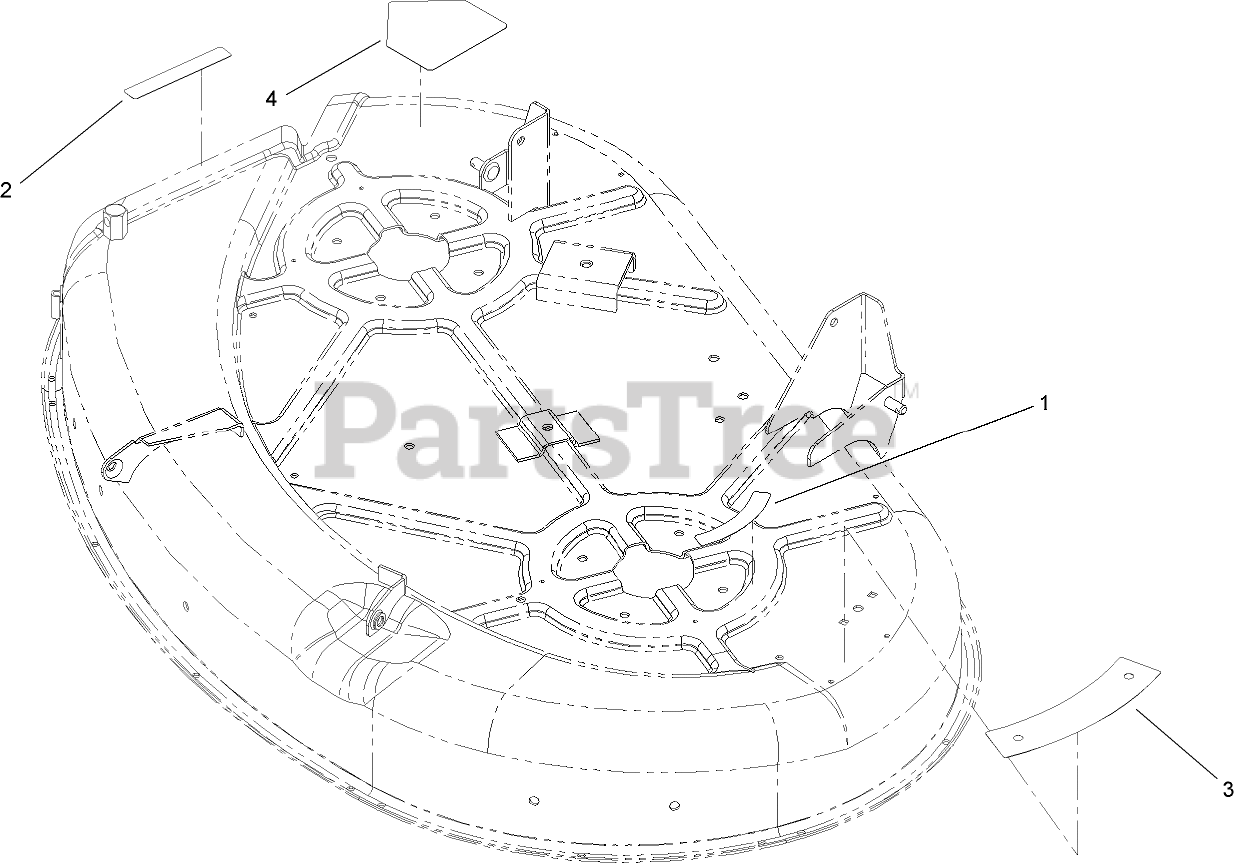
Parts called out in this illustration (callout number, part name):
1	DECAL-DANGER, SHIELD
2	DECAL-DANGER
3	DECAL-DANGER
4	DECAL-DANGER
